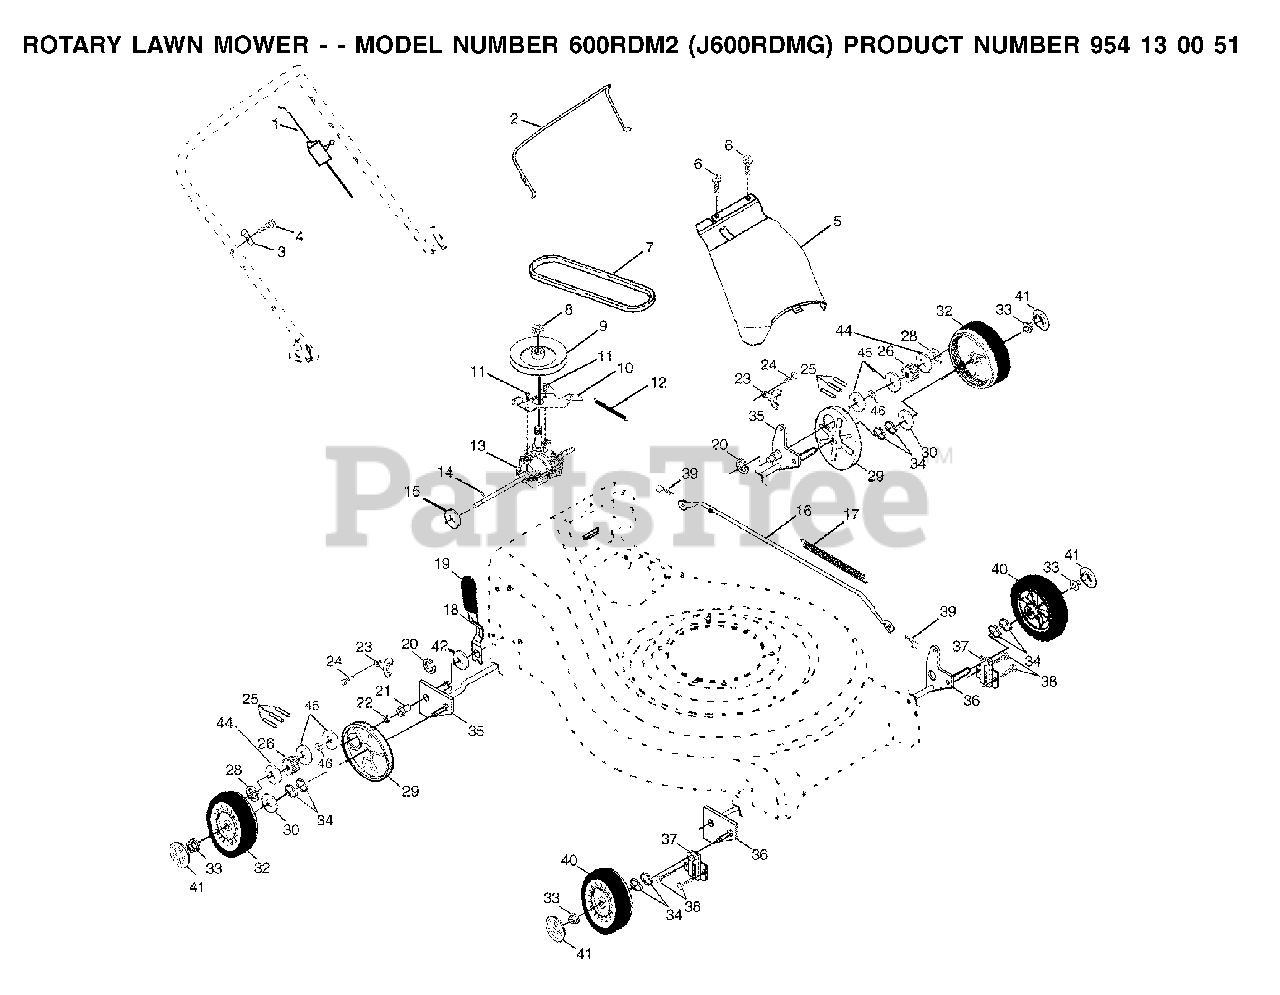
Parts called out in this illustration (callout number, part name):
1	CABLE DRIVE
2	BAIL.CONT.DR.21.RWGD.BLACK
3	DOWNSTOP BRACKET
4	SCREW.HEX.HEAD.WASHER.10-16
5	DRIVE COVER
8	FLANGED LOCKNUT 3/8-16 ZINC
13	TRANSMISSION ASM. (WALK)
14	PIN.SPRING.THRUST
15	THRUST WASHER
16	ROD CONNECTING
17	SPRING
18	SPRING
19	KNOB
21	RP BEARING SUPPORT
22	BEARING, BALL
23	BRACKET
26	DRIVE PINION
28	E-RING 7/16 RE
29	DUST COVER, WHEEL
30	WASHER FLUT
32	WHEEL, 9 X 2
33	HEX FLANGE LOCKNT
34	WAVE WASHER
35	SHAFT ASSY
36	SHAFT ASSY
37	RETAINER.FRONT.SHAFT
39	RETAINER CLIP
40	WHEEL ASMBLY FRONT
41	CAP.HUB.ARC.SPOKE.8".LP
44	WASHER
45	BELLEVILLE WASHER
